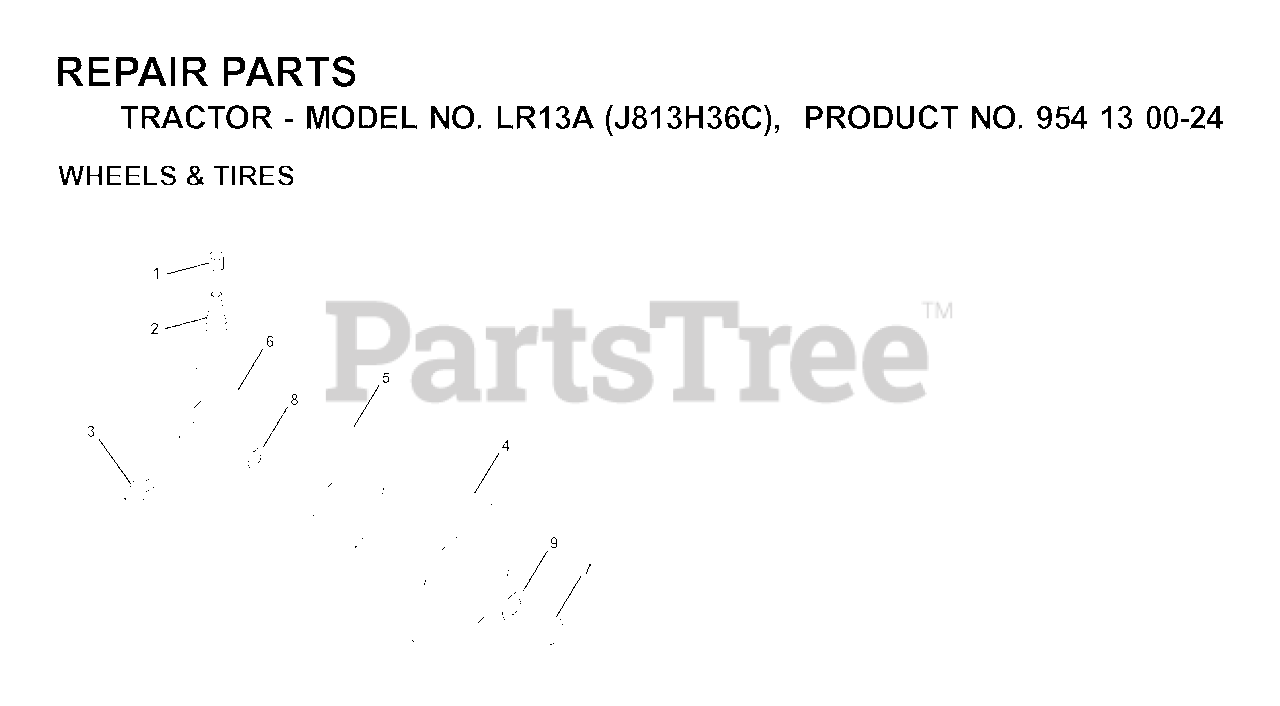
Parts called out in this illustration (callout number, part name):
1	VALVE CAP
2	VALVE STEM LT
3	FITTING LT
4	TIRE FRONT 15X6-6
4	REAR TIRE
5	TUBE.5.3/4.5/6
5	TUBE.16X6.5/7.5-8
6	RIM
6	RIM REAR 8"
7	CAP-HUB FRONT LT
8	BEARING T
